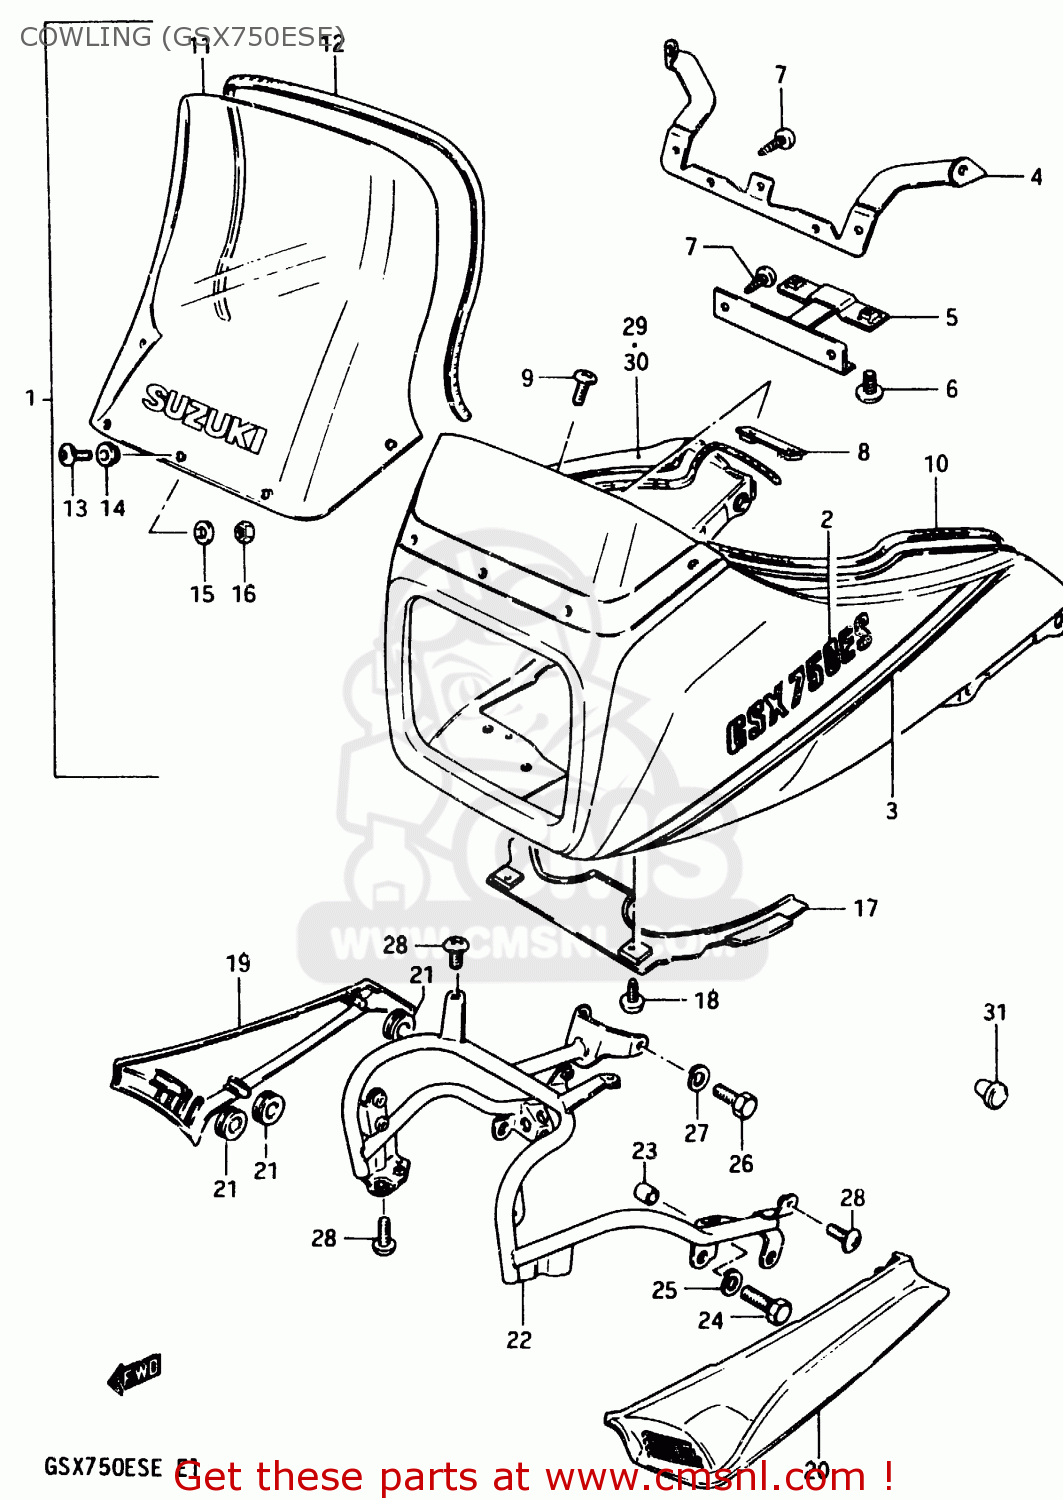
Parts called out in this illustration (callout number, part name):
1	COWLING ASSY (WHITE/RED)
2	EMBLEM
3	TAPE SET
4	BRACE,COWLING,UPPER
5	BRACE,COWLING,LOWER
6	SCREW
7	SCREW
8	BRACKET
9	SCREW
10	MOLDING,FUEL TANK
11	WINDOW
12	MOLDING
13	SCREW
14	CUSHION
15	WASHER
16	NUT
17	COVER,COWLING,LOWER
18	SCREW
19	COVER,COWLING,RIGHT
20	COVER,COWLING,LEFT
21	CUSHION
22	BRACE,COWLING
23	SPACER,COWLING
24	BOLT, LOWER
25	LOCK WASHER
26	BOLT
27	LOCK WASHER
28	SCREW 6X12
29	TAPE,RIGHT
30	TAPE,LEFT
31	PLUG(OD:12)
